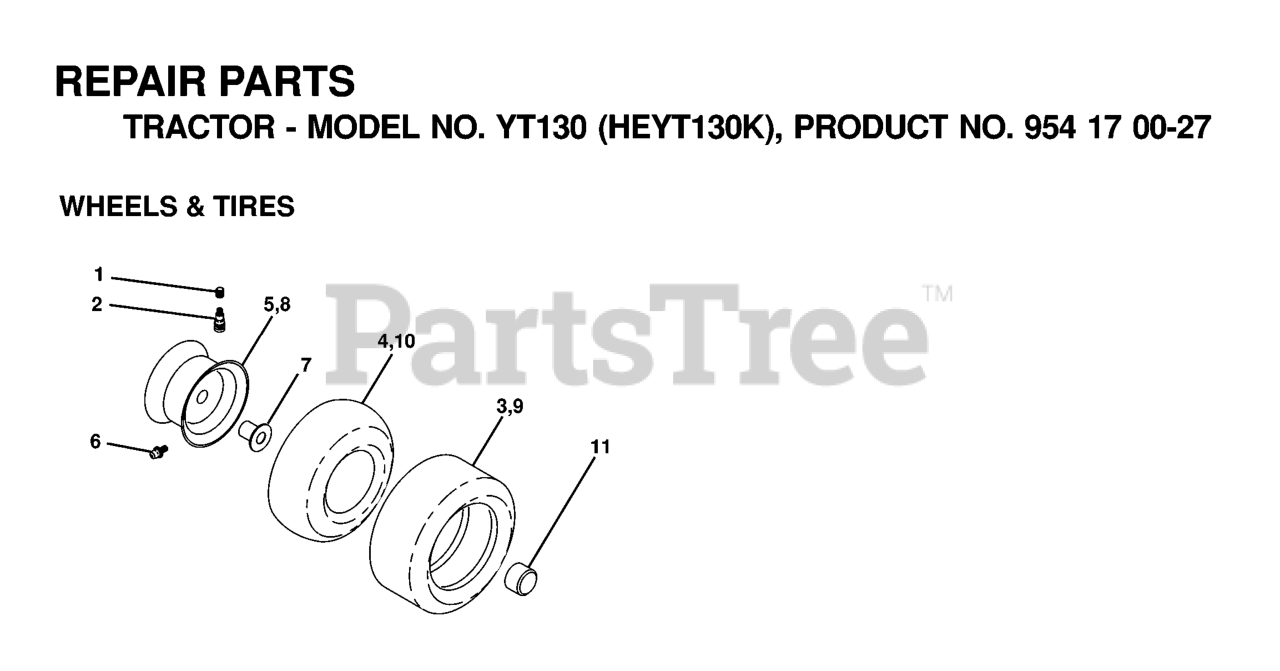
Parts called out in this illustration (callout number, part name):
1	Bracket- Spring Retainer
2	Pulley- Blade Brake/Clutch
3	SPRING TENSION .043X.44X3.31
4	Screw-Socket Head-Special .375-24 x 1.50
5	Washer-Wave .88 x 1.31 x .125
6	RECOIL START HANDLE
8	Blade Brake Clutch
9	Screw-Tapping .38-16 x 1.00 Hex Washer Head
10	KEY WOODRUFF .156 X .625 X .25
11	V-BELT 3L SECTION
12	BOLT HEX .44-14 X 1.25 GRADE 5
13	IDLER FLAT 1.75 X .47
14	NUT-LOCKING-CENTER .31-18
15	WASHER FLAT STL .323X.625X.062
16	Bushing-Sleeve .469 x .750 x .430
18	BSHNG FLG .325X.501X.250X1.120
19	BOLT-HEX .31-18 X .75 GRADE 5
20	NUT LOCKING CENTER .44-14
21	SPRING TENSION .043X.44X3.31
22	BLADE, 580BBC
23	Washer-Locking .44 x .109 Regular
24	Bolt-Hex M10 x 1.5 x 25
